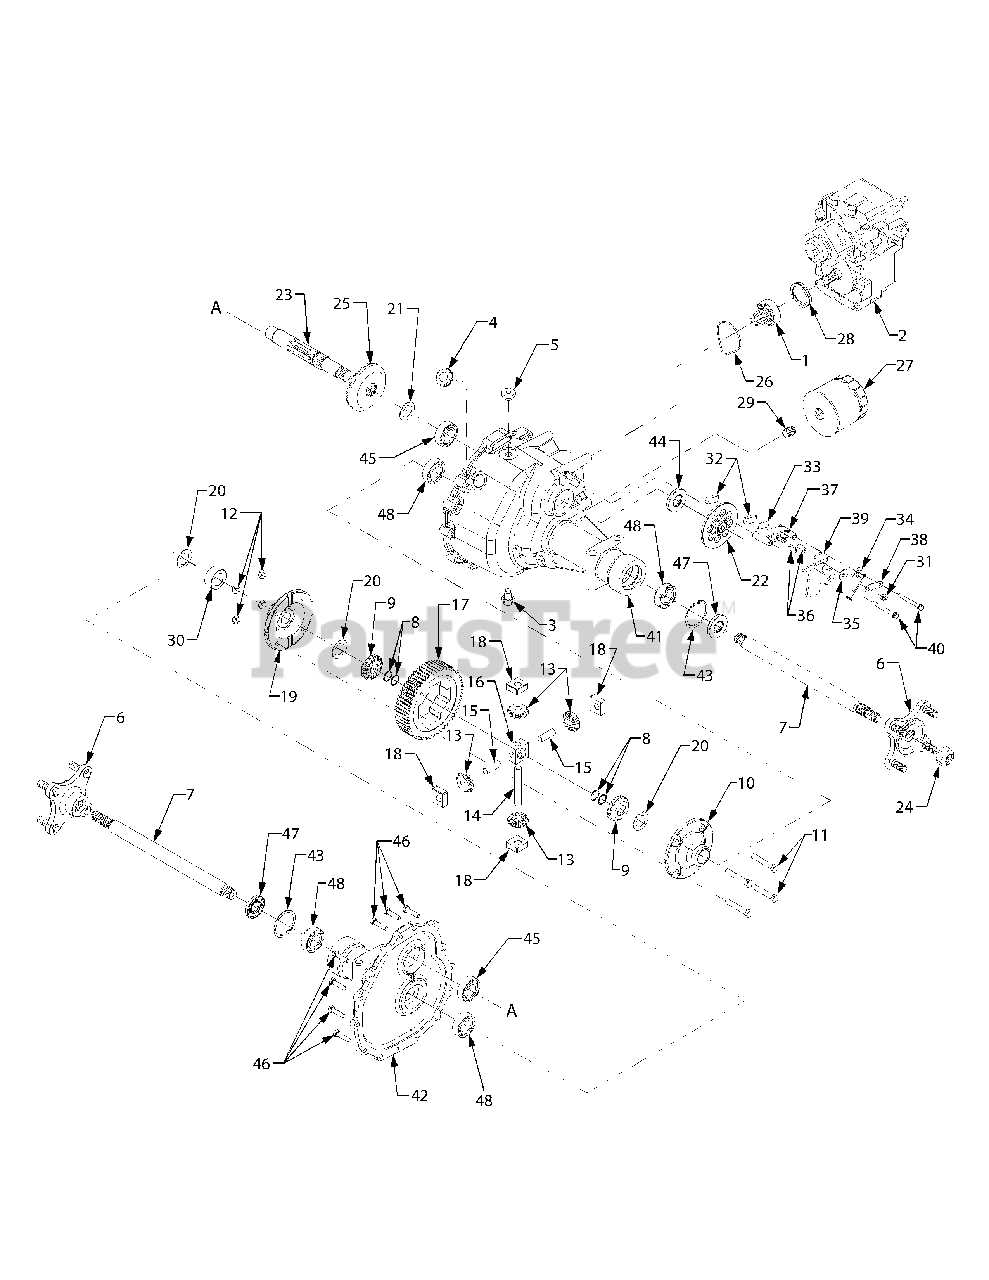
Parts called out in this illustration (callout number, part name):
1	Gear Assembly, Pinion 13T
1	Bearing, Ball
2	Hydrostatic Transmission Assy.
3	Plug, Drain, M14 x 1.5 x .827
4	Grommet, Rubber
6	Hub Assembly, Wheel
7	Axle Shaft, 1.181 x 15.08
8	Retaining Ring
9	Gear, Spur, 14T
10	Housing, Diff. Cover RH
11	Hex Cap Screw, 3/8-24 x 2.25 GR5
12	Nut, Hex Lock, 3/8-24
13	Gear, Differential 10T
14	Shaft, Cross, .5 x 3.485
15	Shaft, Cross, Special
16	Differential Pinion Block
17	Gear, Spur 60T
18	Block, Thrust Miter
19	Housing, Differential Cover LH
20	Washer, Flat, 1.187 x 1.56 x .062
21	Washer, Flat, 1.0 x 1.56 x .030
22	Disc, Brake
23	Shaft, Output 9T
24	Nut, Lock, 7/8-14
25	Gear, Bevel 54T
26	Seal, Gland O-Ring
27	Filter, Oil
28	Washer, Spring
29	Fitting, Filter Nipple
30	Spacer, Axle, 1.188 x 1.665 x .67
31	Nut, Hex Insert Lock, 5/16-24
32	Pad, Brake
33	Plate, Puck
34	Spring, Torsion
35	Washer, Flat, .343 x .88 x .062
36	Pin, Brake Actuator
37	Yoke, Brake
38	Bracket, Brake Anti-Rotation .
39	Arm, Brake Actuator
40	Screw, Hex Wash. Hd. Tapp 1/4-20 x 2.375
41	Housing, RH
42	Housing, LH
43	Retaining, Ring
44	Seal, Oil, 1.0 ID
45	Bearing, Ball
46	Screw, Hex Cap Locking .5/16-18 x 1.25 GR5
47	Seal, Oil, 1.18 ID
48	Bearing, Ball
